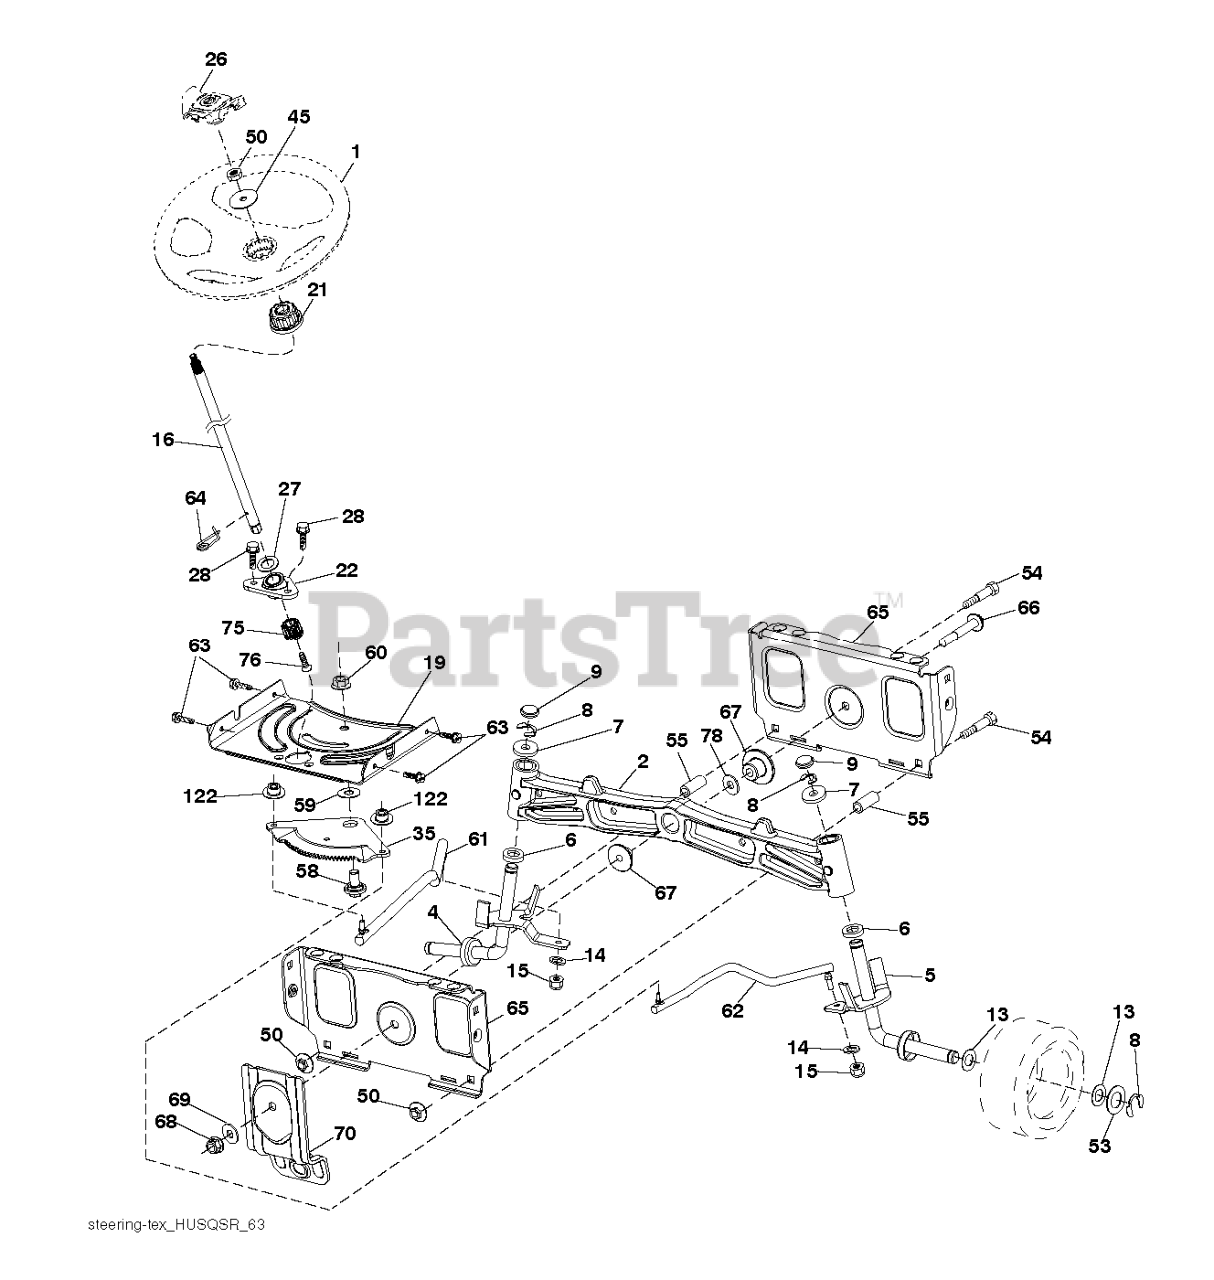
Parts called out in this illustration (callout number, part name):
1	WHEEL.STEER.HUSQ.SR.498.OVMLD
2	AXLE.CAST.IRON
4	SPINDLE.WELDED.LH.16"TEX
5	SPINDLE.WELDED.RH.16"TEX
6	THRUST WASHER
9	CAP.SPINDLE.BLACK
14	WASHER, LOCK 3/8
15	NUT CROWNLOCK 3/8-24
16	SHAFT.STEER.2HIGH.SPLND.PLATED
19	PLATE.STEER.DDL.NLT/NG
21	ADAPTER.WHEEL.STEER.SPLND.ALUM
22	BEARING.SHAFT.STEER.LOWER.625
26	INSERT.CAP.WHL.STRG.HUSQ.PREM
27	WASHER LT
28	SCREW, 3/8-16X3/4
35	GEAR.SECTOR.PLATE.DDL.
45	WASHER.3/8ID.2-3/8OD.12GA.PLTD
50	NUT LOCK FLG 3/8-16 UNC
53	WASHER.HARDENED
55	SPACER.BRACE.AXLE
58	BOLT.SHOULDER.SECTOR.P
59	WASHER.THURST.SECTOR.S
60	NUT FLANGE LOCK 5/8-11
61	DRAGLINK.LH.BALLSTUD.D
62	DRAGLINK.RH.BALLSTUD.D
63	SCREW
64	RETAINER.CLIP.SPRING.S
65	BRACE.AXLE.FRONT.NLT/N
66	BOLT HEX FGHD 7/16-14 X 3 SERR
67	BUSHING.PM.FRONT AXLE
68	NUT.LOCK.FLANGE.7/16
69	WASHER.1.5X.505X.118
70	BRACKET.FRT.DECK.SUSP.RR.MT431
75	PINION.ZINC PLATED
76	SCREW HEAD SOCKET LRVB
78	THRUST WASHER
122	CAP.GEAR.SECTOR.TEX
